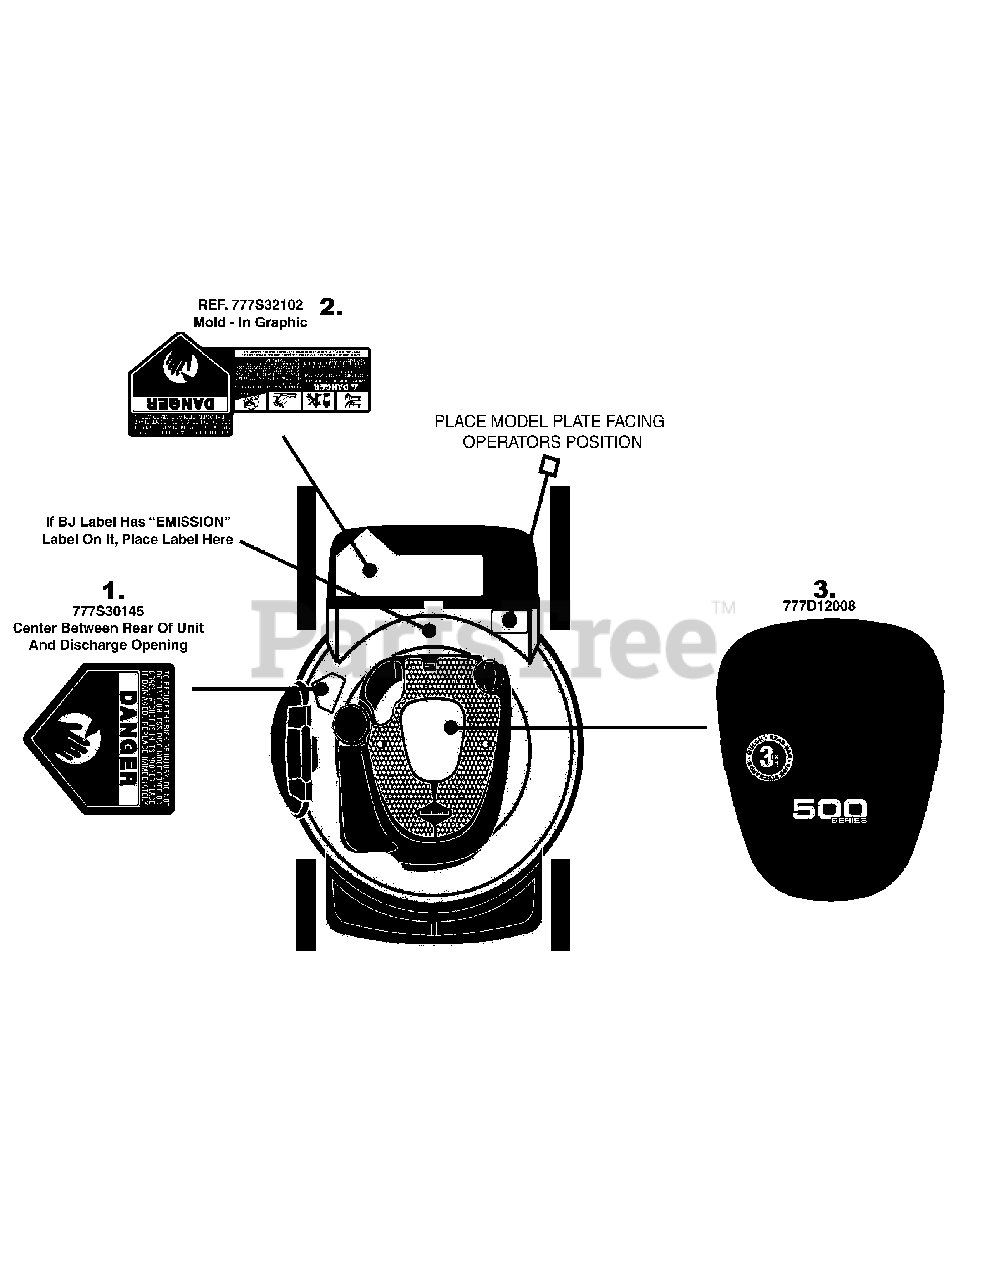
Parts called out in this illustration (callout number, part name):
1	LABEL
2	LABEL
3	LABEL-MOWER SHROUD MTD GOLD 3 IN 1
